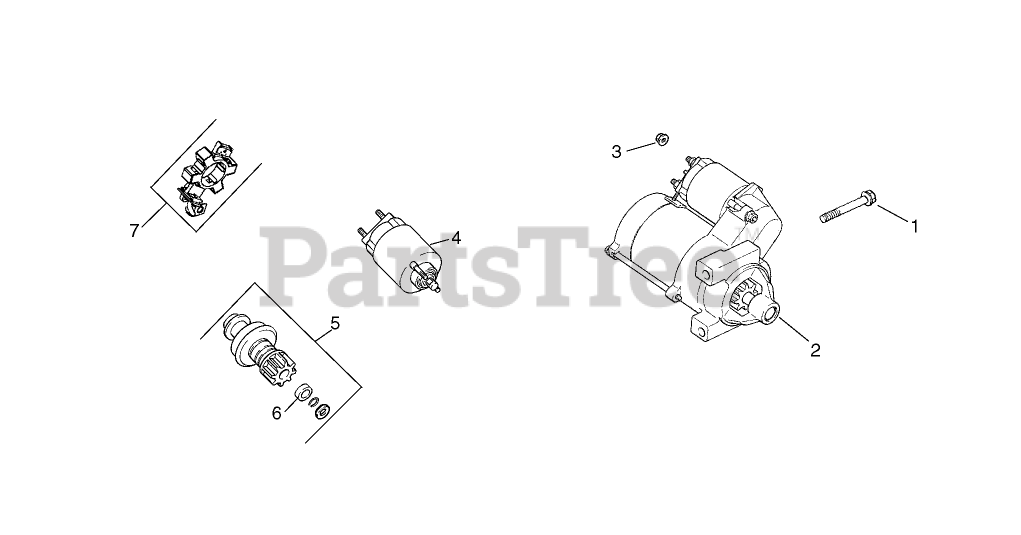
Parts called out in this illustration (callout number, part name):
1	SCREW-FLG (M8X1.25X80)
2	Starter, solenoid shift ASM (Includes 4-7)
3	NUT-FLANGE (M8X1.25)
4	Solenoid Kit
5	Kit, pinion drive (Includes 6)
6	RING-RETAINING
7	BRUSH HOLDER KIT
